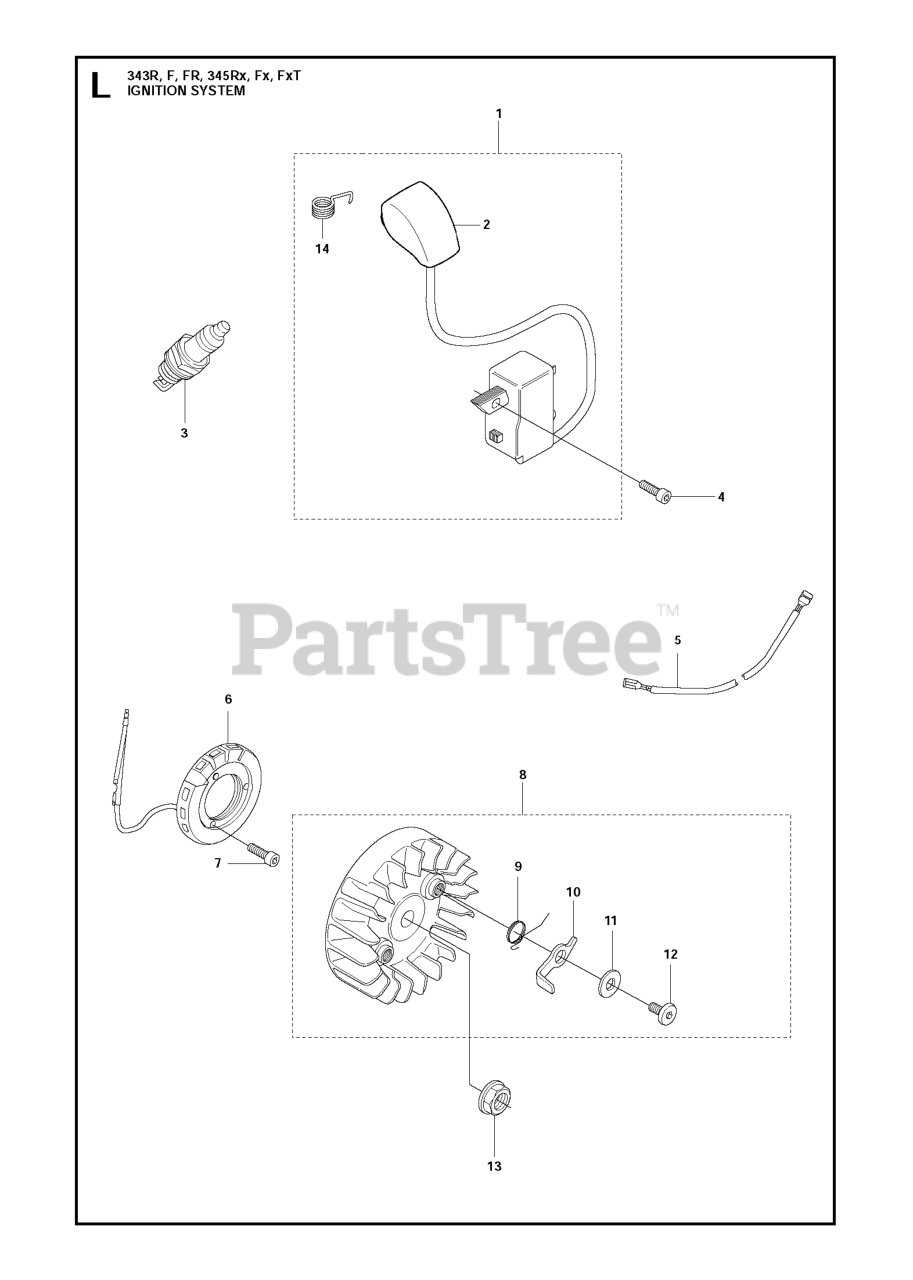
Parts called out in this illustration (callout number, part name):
1	IGNITION MODULE
3	SPARK PLUG RCJ6Y NLA
5	SHORTING LEAD
6	GENERATOR
7	SCREW
8	FLYWHEEL
8	Flywheel
9	SPRING
10	STARTER PAWL
13	NUT W/ WASHER
14	SPRING
